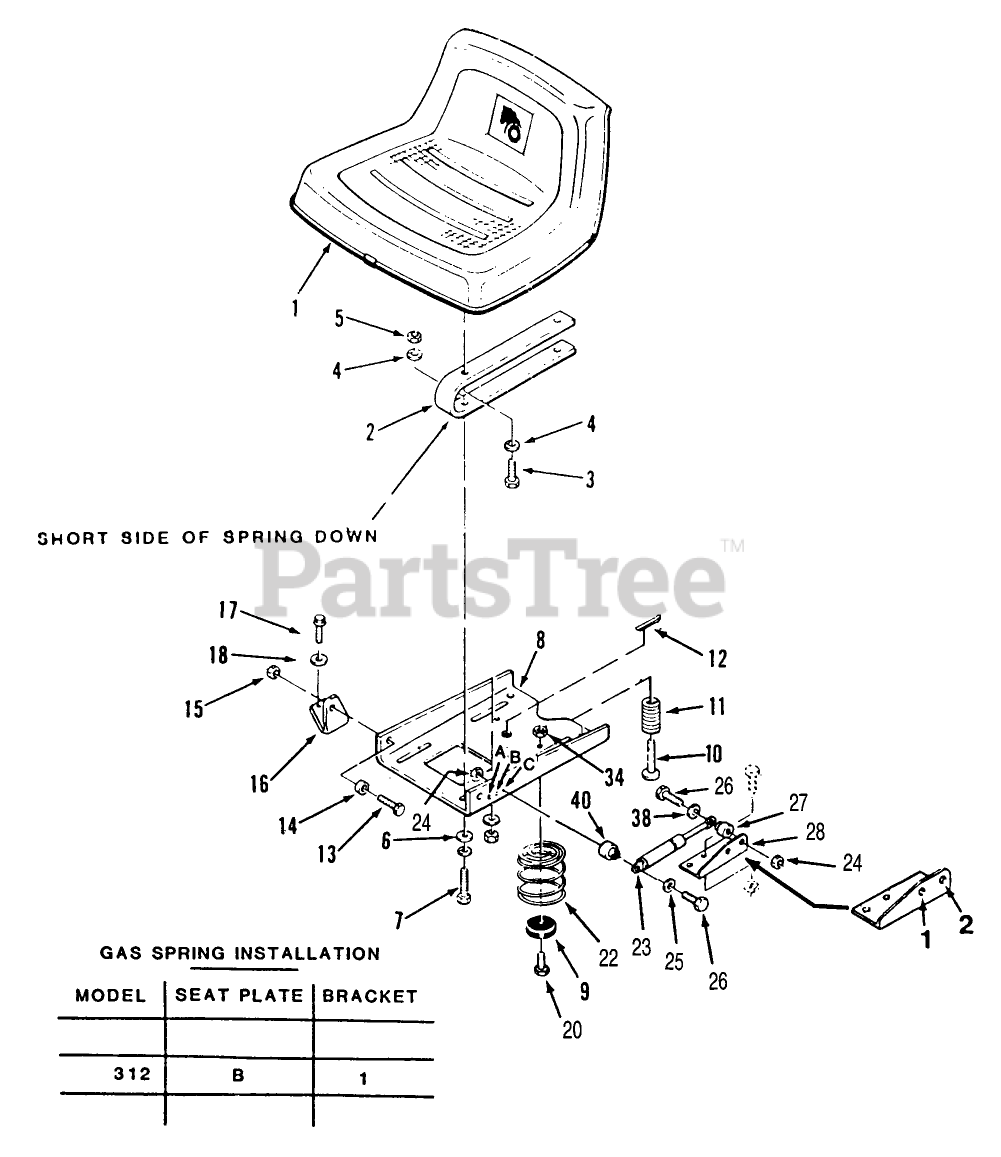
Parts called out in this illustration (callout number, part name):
6	WASHER 5/16 SAE
9	BUMPER
11	SPRING-SEAT SWITCH
14	BUSHING
16	BRACKET-PIVOT R.H *B (NS)
18	WASHER 5/16 SAE
23	GAS SPRING
27	SPACER
28	BRACKET-CYLINDER *R
